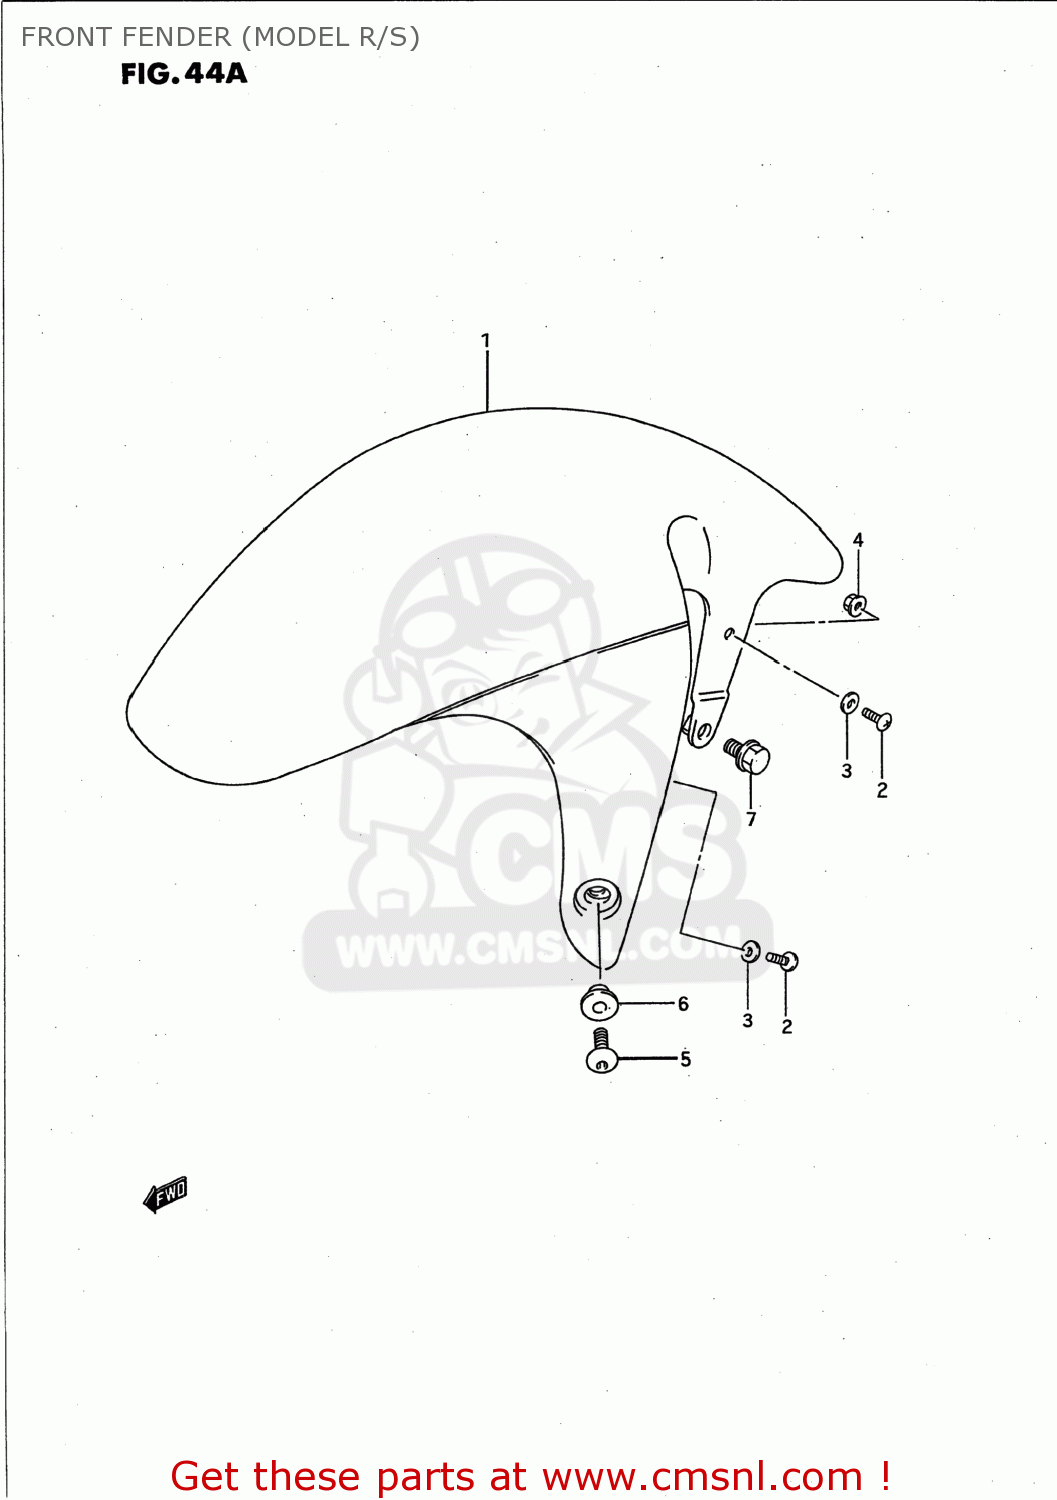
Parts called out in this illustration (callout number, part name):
1	FENDER,FR
2	SCREW
3	WASHER
4	NUT
5	SCREW(6X16)
6	WASHER(6.3X16X1.5)
7	BOLT
